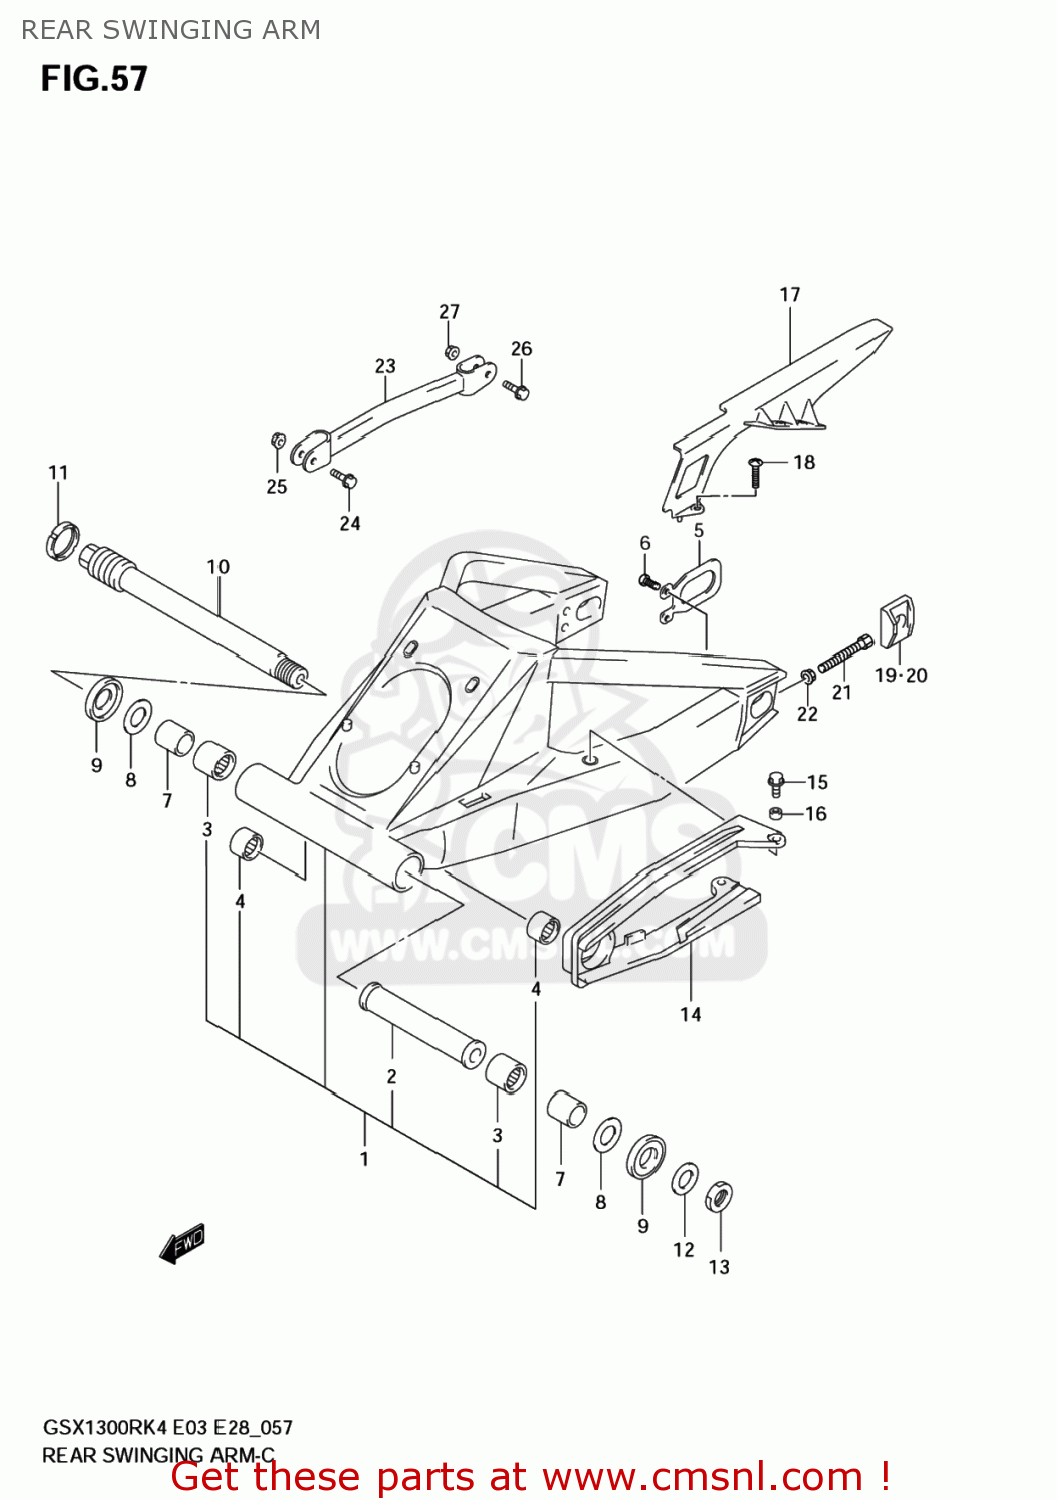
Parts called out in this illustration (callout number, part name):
1	SWINGINGARM ASSY,RR
2	SPACER,REAR SWING PIVOT,CENTER
3	BEARING(30X40X25)
4	BEARING(20X27X23.5)
5	PLATE,RR SWING ARM BRKT
6	SCREW
7	SPACER,REAR SWING ARM PIVOT
8	WASHER
9	DUST SEAL,RR SWGARM PIVOT
10	SHAFT,RR SWINGINGARM PIVOT
11	NUT,RR SWGARM PIVOT BOLT
12	WASHER(25.2X42X3.2)
13	NUT
14	BUFFER,CHAIN TOUCH DEFENSE
15	BOLT(6X20)
16	SPACER(6.5X9X5)
17	CASE,CHAIN
18	SCREW(6X16)
19	ADJUSTER,CHAIN,L
20	ADJUSTER,CHAIN,R
21	BOLT(8X50)
22	NUT
23	TORQUELINK,RR
24	BOLT(8X35.5)
25	NUT
26	BOLT(10X37)
27	NUT
